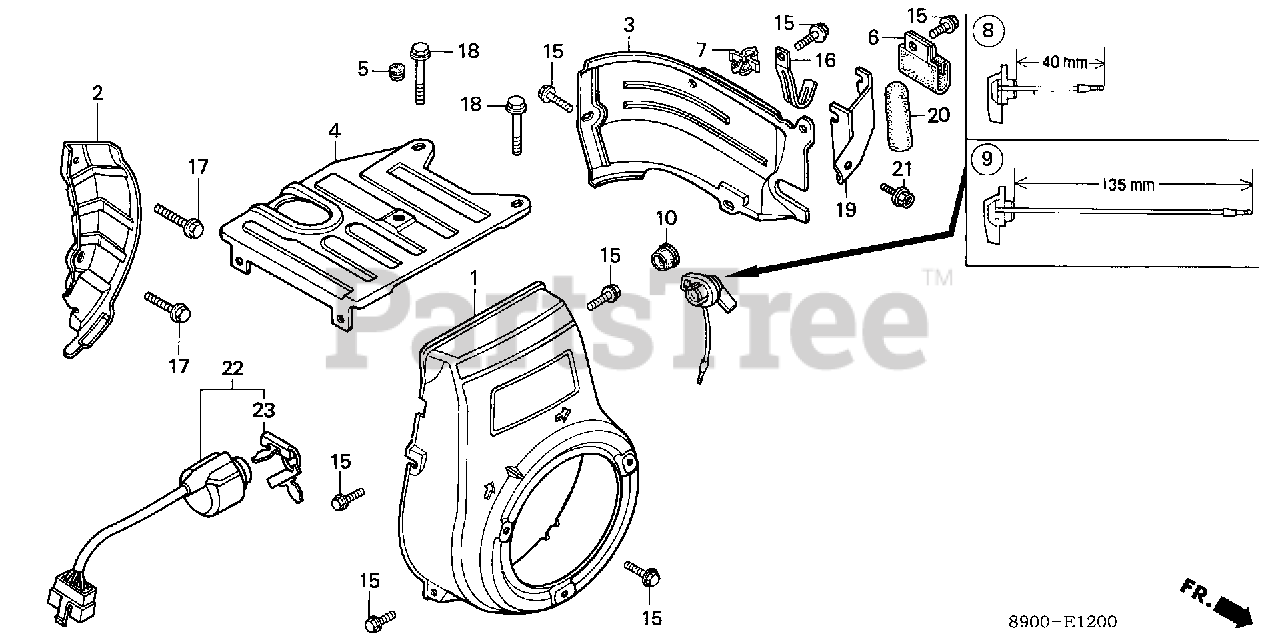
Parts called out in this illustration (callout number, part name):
1	COVER, FAN *R8* (BRIGHT RED) (NOT AVAILABLE)
2	PLATE, SIDE
3	SHROUD *R8* (BRIGHT RED)
4	COVER, TOP *R8* (BRIGHT RED)
5	GROMMET, TOP COVER
7	CLIP, IGNITION WIRE (8MM)
9	SWITCH ASSY., ENGINE STOP
15	BOLT, FLANGE (6X12) (CT200)
16	CLIP, WIRE HARNESS
17	BOLT, FLANGE (8X20)
22	SWITCH ASSY., COMBINATION
23	KEY
